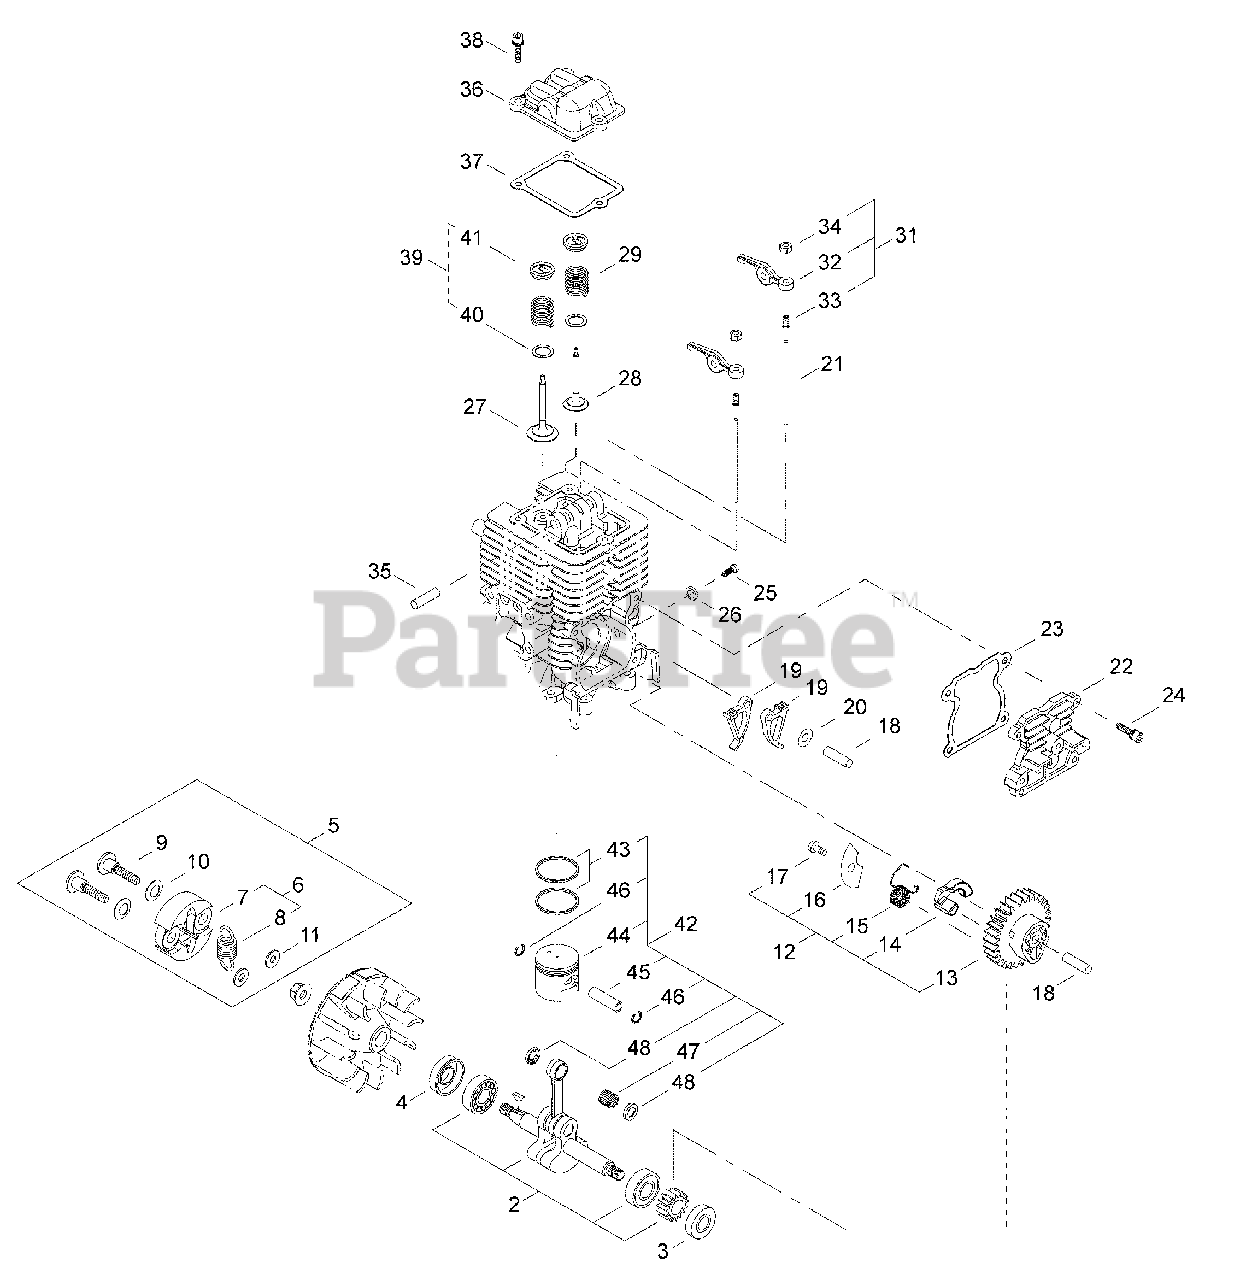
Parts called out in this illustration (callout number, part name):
2	CRANKSHAFT ASSY
3	SEAL, OIL 12
4	SEAL, OIL 12
5	CLUTCH ASSY
6	SHOE ASSY, CLUTCH
7	SHOE, CLUTCH
8	SPRING, CLUTCH
9	BOLT, CLUTCH
10	WASHER, SPRING
11	WASHER 6 MM
12	CAM GEAR ASSY
13	GEAR, CAM
14	WEIGHT
15	SPRING
16	PLATE, COVER
17	SCREW, TAPPING 4×6
18	PIN, LOCATING Ø5×29.8 MM
19	FOLLOWER, CAM
20	WASHER 5 MM
21	PUSHROD
22	COVER, CAM GEAR
23	GASKET, CAM GEAR
24	BOLT M4×14
25	SCREW M5
26	WASHER Ø10ר5.5×2
27	VALVE, INTAKE
28	VALVE, EXHAUST
29	SPRING, VALVE
31	ARM ASSY, ROCKER
32	ARM, ROCKER
33	SCREW, ADJUSTER
34	NUT, ADJUSTER LOCK 5
35	SHAFT, ROCKER ARM Ø5×37.8 MM
36	COVER, ROCKER ARM
37	GASKET, ROCKER ARM
38	BOLT M4×14
39	RETAINER SET, VALVE
40	WASHER, VALVE 9
41	RETAINER, VALVE
42	PISTON KIT
43	RING, PISTON
44	PISTON
45	PIN, PISTON 10
46	RING, SNAP
47	BEARING, NEEDLE 10
48	WASHER, THRUST 10
